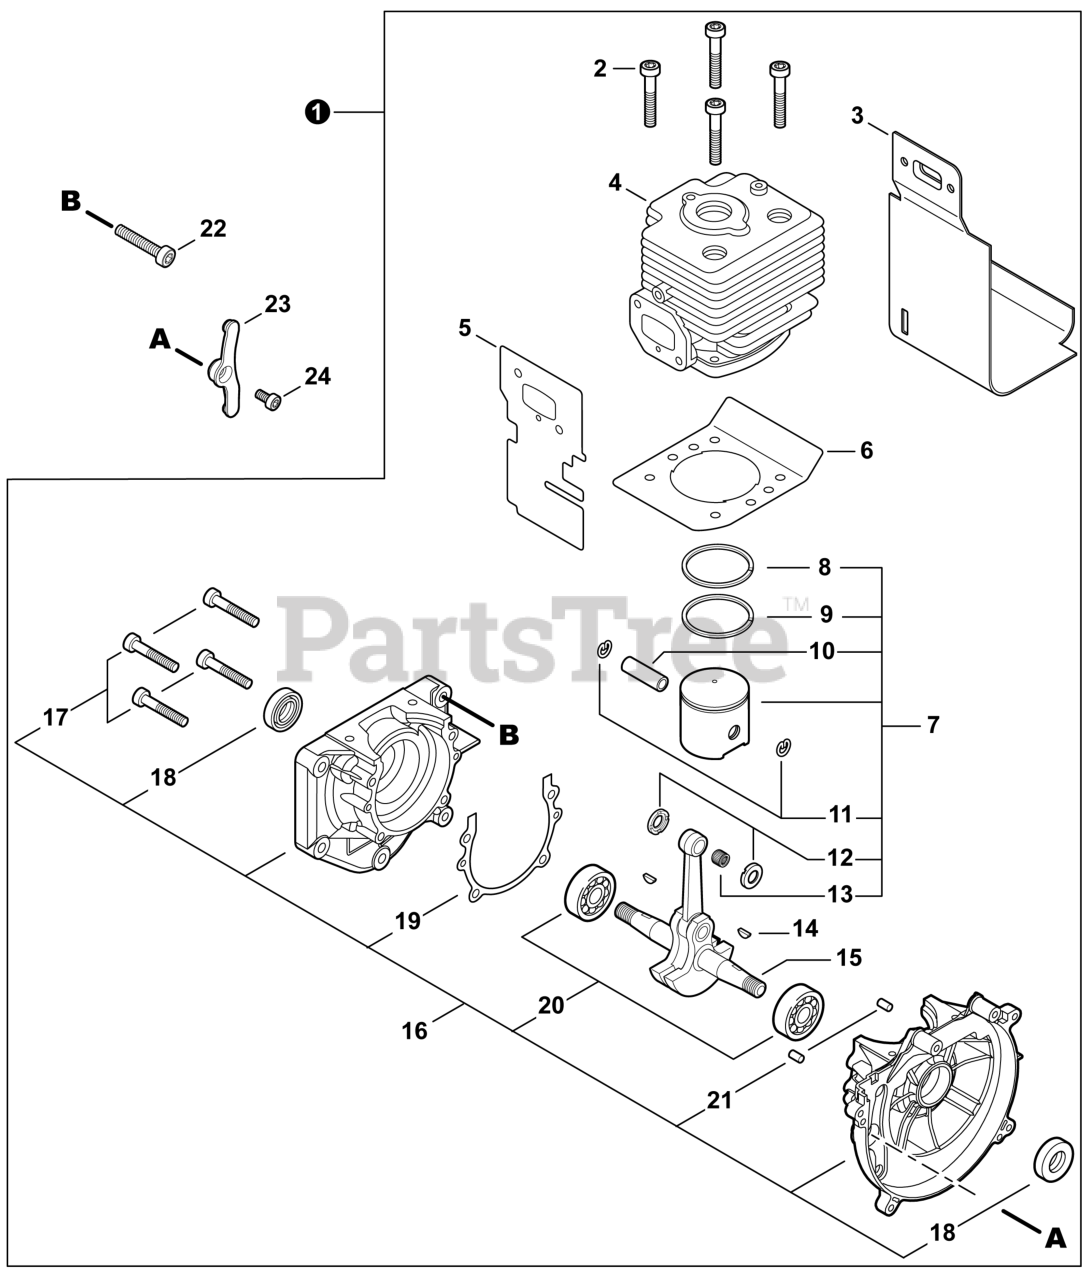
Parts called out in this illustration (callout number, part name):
1	SHORT BLOCK
2	BOLT, TORX 5x25
3	HEAT SHIELD, EXHAUST
4	CYLINDER
5	HEAT SHIELD, INTAKE
6	GASKET, CYLINDER
7	PISTON KIT
8	RING, PISTON
9	RING, PISTON
10	PIN, PISTON
11	RING, SNAP 8
12	WASHER, THRUST
13	BEARING, NEEDLE 10
14	KEY, WOODRUFF 3x14
15	CRANKSHAFT ASSY
16	CRANKCASE KIT
17	BOLT, TORX 5x30
18	SEAL, OIL 15
19	GASKET, CRANKCASE
20	BEARING, BALL 6302
21	PIN, LOCATING 4x8
22	BOLT, TORX 6x30
23	COVER, DUST
24	BOLT, TORX 5x10
